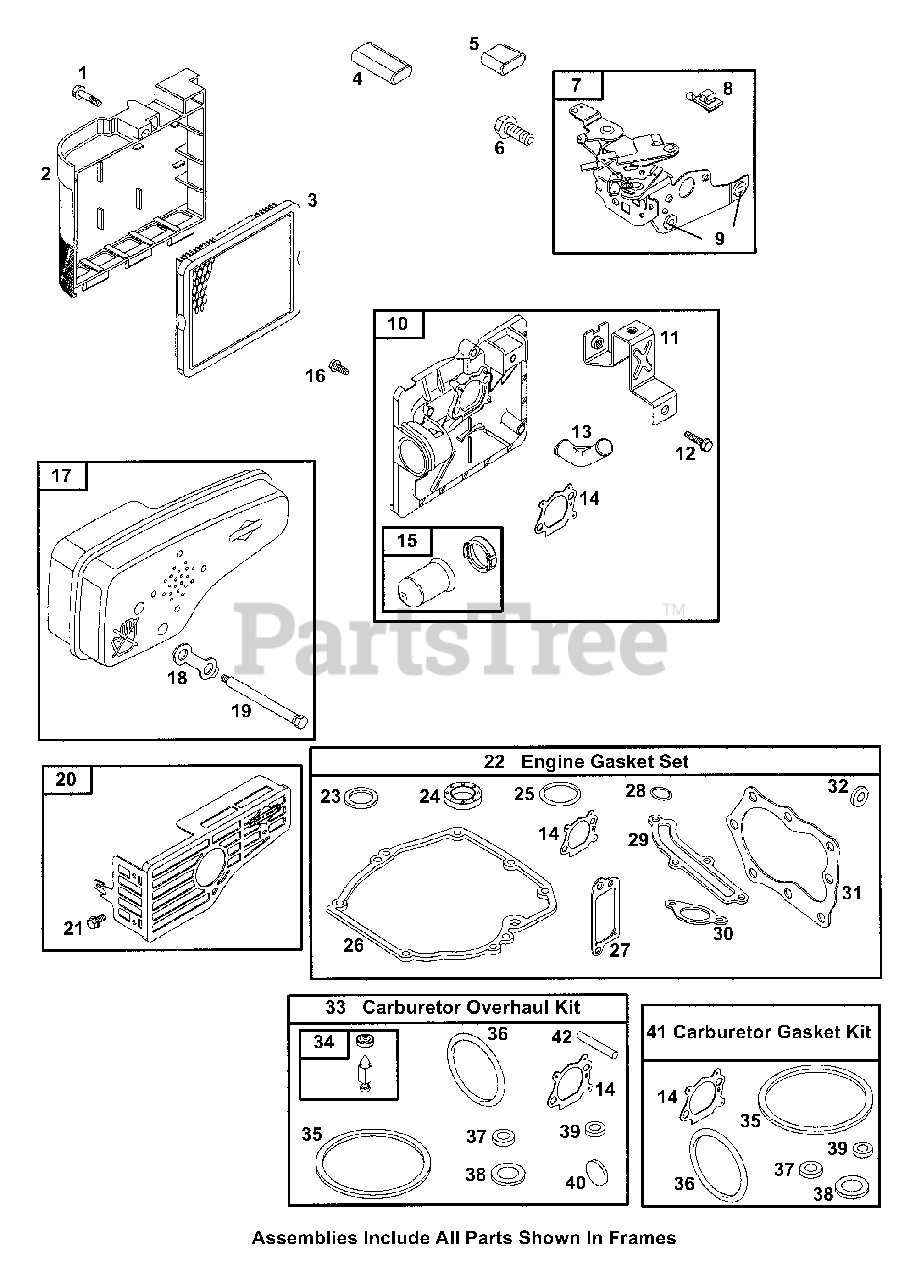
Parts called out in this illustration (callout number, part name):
1	Screw (Air Cleaner Cover)
2	Air Cleaner Cover
3	Air Cleaner Cartridge Filter
4	Lever Sleeve
5	Lever Sleeve
6	Screw (Control Bracket)
7	Control Bracket
8	Stop Switch
9	Spacer
10	Primer Base
11	Air Cleaner Primer Bracket
12	Screw (Support Bracket)
14	Air Cleaner Gasket
15	Carburetor Primer
16	Screw (Primer Base)
17	Exhaust Muffler
18	Muffler Screw Lock
19	Screw (Exhaust Muffler)
20	Muffler Guard
21	Screw (Muffler Guard)
22	Gasket Set
23	Oil Seal
24	Oil Seal
25	Dipstick/Tube Seal
26	Crankcase Gasket
27	Breather Gasket
28	Dipstick Tube Seal
29	Breather Passage Gasket
30	Intake Gasket
31	Cylinder Head Gasket
32	Spacer
33	Carburetor Overhaul Kit
34	Needle/Seat Kit
35	Float Bowl Gasket
36	O-Ring Seal (Intake Manifold)
37	Choke Shaft Seal
38	Sealing Washer
39	Throttle Shaft Seal
40	Welch Plug
41	Carburetor Gasket Set
42	Float Hinge Pin
